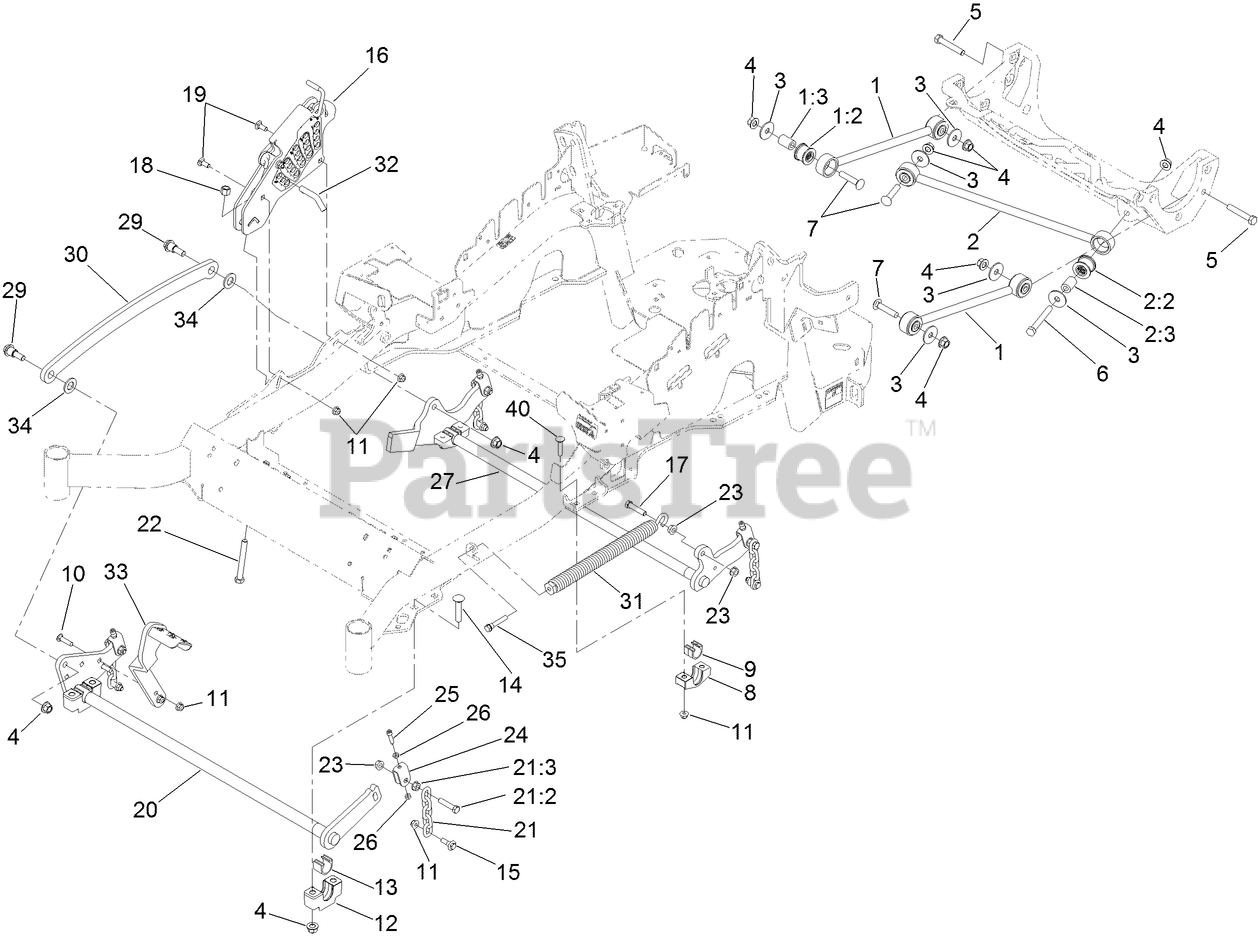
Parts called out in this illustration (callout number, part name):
1	DECK STRUT ASM
1:2	BUSHING-SUSPENSION, RUBBER
1:3	SPACER
2	PANHARD ROD ASM
2:2	BUSHING-SUSPENSION, RUBBER
2:3	SPACER
3	WASHER-THRUST
4	NUT-LOCK
5	SCREW-HH
6	SCREW-HH
7	SCREW-CARR
8	SUPPORT-CROSS SHAFT, REAR BEARING
9	BEARING-CROSS SHAFT, REAR
10	SCREW-CARR
11	NUT-HF, NI
12	SUPPORT-CROSS SHAFT, BEARING
13	BEARING-CROSS SHAFT, FRONT
14	BOLT-CARR
15	SCREW-SHOULDER, HHF
16	HOC ASM
17	SCREW-HH
18	NUT-LOCK, NI
19	BOLT-CARR
20	CROSS SHAFT-FRONT
21	DECK LIFT CHAIN ASM
21:2	SCREW-HH
21:3	NUT-HF
22	BOLT-TAP
23	NUT-HF
24	YOKE-ADJUST, DECK
25	SCREW-HSH
26	NUT-JAM
27	LIFT-DECK, REAR
29	SCREW-SHOULDER, HHF
30	LINK-LIFT, DECK
31	SPRING-EXTENSION
32	PIN-HOC
33	LEVER-FOOT
34	WASHER-FLAT
35	BOLT-SHOULDER
40	SCREW-CARR
